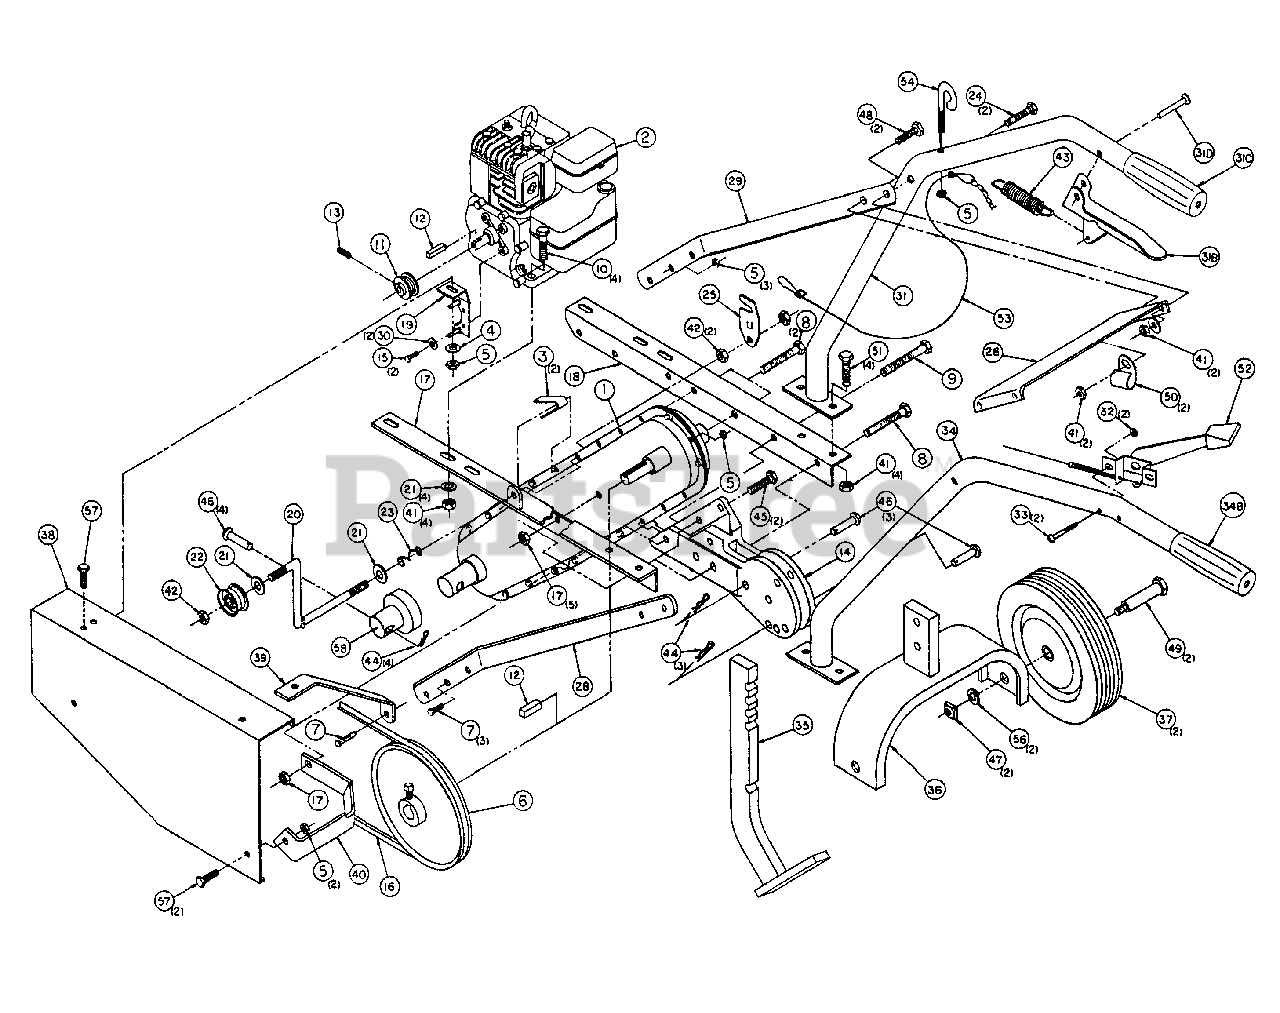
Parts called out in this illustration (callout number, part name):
1	Transmission Assembly
2	* ENGINE
3	"U" Shaped Spacer
4	1/4" Flat Washer
5	1/4-20 Nylok Locknut
6	Pulley - Transmission
7	1/4-20 x 1" HHCS
8	5/16-18 x 2-3/4" HHCS
9	5/16-18 x 3" HHCS
10	5/16-18 x 1-3/4" HHCS
11	Pulley - Engine
12	3/16 x 3/16 x 1" Shaft Key
13	5/16-18 x 5/16" Set Screw
14	Hitch - Rear
15	5/16-24 x 3/4" HHCS
17	L.H. Engine Mount
18	R.H. Engine Mount
19	Belt Release Bracket
20	Idler Arm
21	5/16 Flat Washer
22	Idler Pulley
23	Idler Arm Compression Spring
24	5/16-18 x 1-3/4" HHCS
25	Adjustment Link
26	Cross Brace
28	Tie Bar L.H.
29	Tie Bar R.H.
30	5/16" Split Lock Washer
31	R.H. Handle Assembly
31B	Clutch Control Lever
31C	Handle Grip
31D	1/4 x 1-3/8" Rivet
32	10-32 Nut
33	10-32 Machine Screw
34	L.H. Handle Assembly
34B	Handle Grip
35	Rear Skid
36	Wheel Frame
38	Belt Cover
39	Trans. Case to Belt Cover Bracket
40	Engine Mount to Belt Cover Bracket
41	5/16-18 Nylok Locknut
42	3/8-16 Hex Nut
43	Clutch Control Spring
44	1/8" Hair Pin
45	5/16-18 x 1-1/4" HHCS
46	Clevis Pin
47	3/8-16 Square Nut
48	5/16-18 x 3/4" HHCS
49	3/8-16 x 2-1/8" Shoulder Bolt
50	Cable Guide
51	5/16-18 x 1, HHCS
52	Throttle Control
53	Clutch Cable Assembly
54	Pull Cord Holder
56	3/8" Split Lock Washer
57	1/4-20 x 3/4" HHCS
